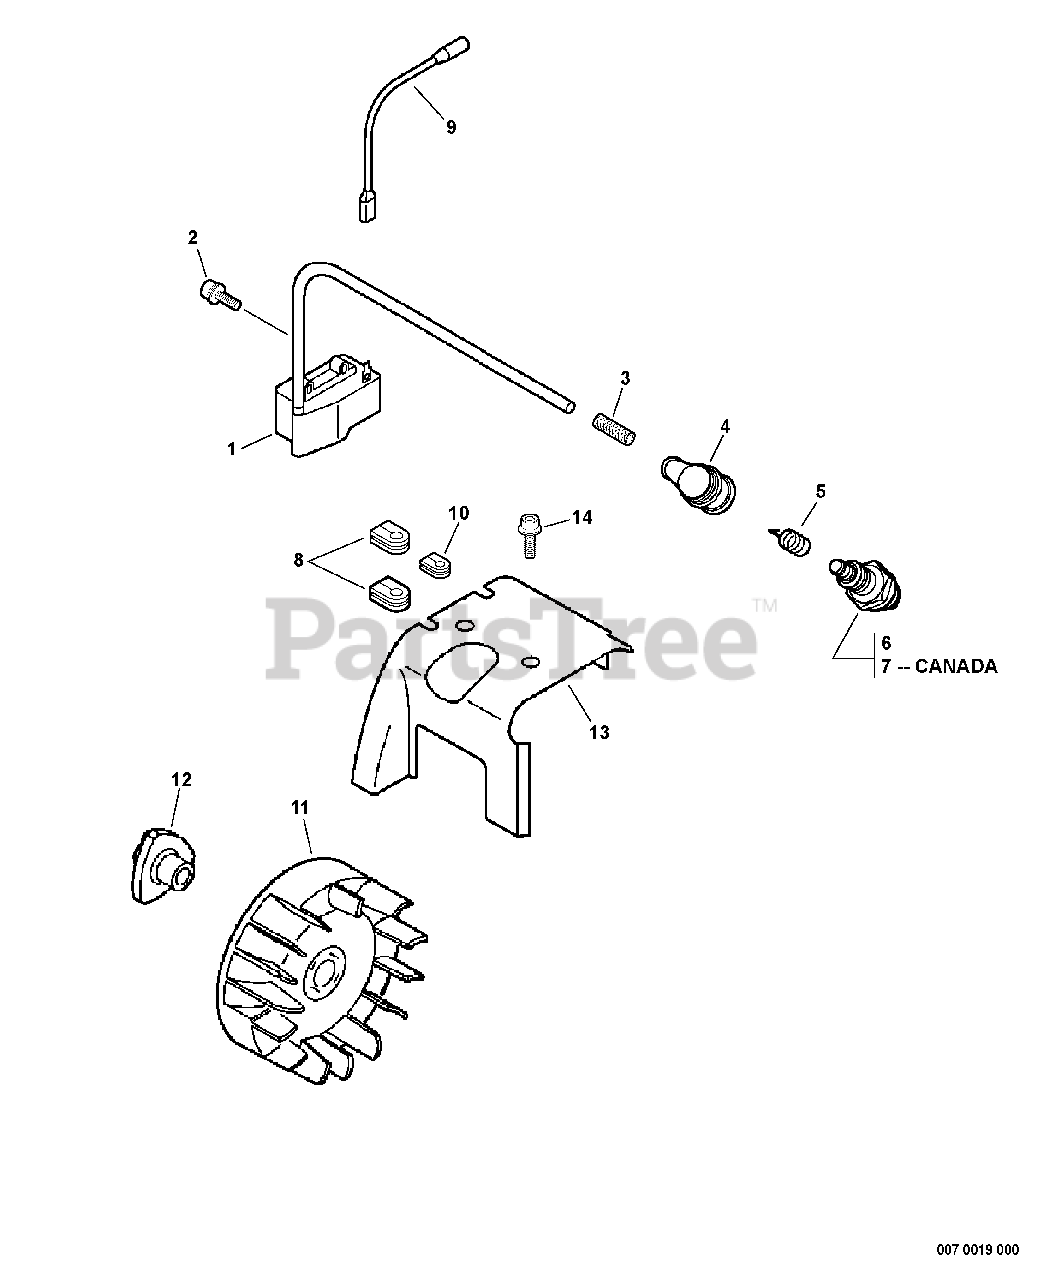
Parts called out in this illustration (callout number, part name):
1	COIL, IGNITION
2	BOLT 4×20
3	TUBE, INSULATOR
4	CAP, SPARK PLUG
5	TERMINAL, SPARK PLUG
6	SPARK PLUG - BPM8Y
7	SPARK PLUG - BPMR8Y
9	LEAD - IGNITION
11	FLYWHEEL
12	HUB, FAN
13	COVER, CYLINDER
14	BOLT 5×8
